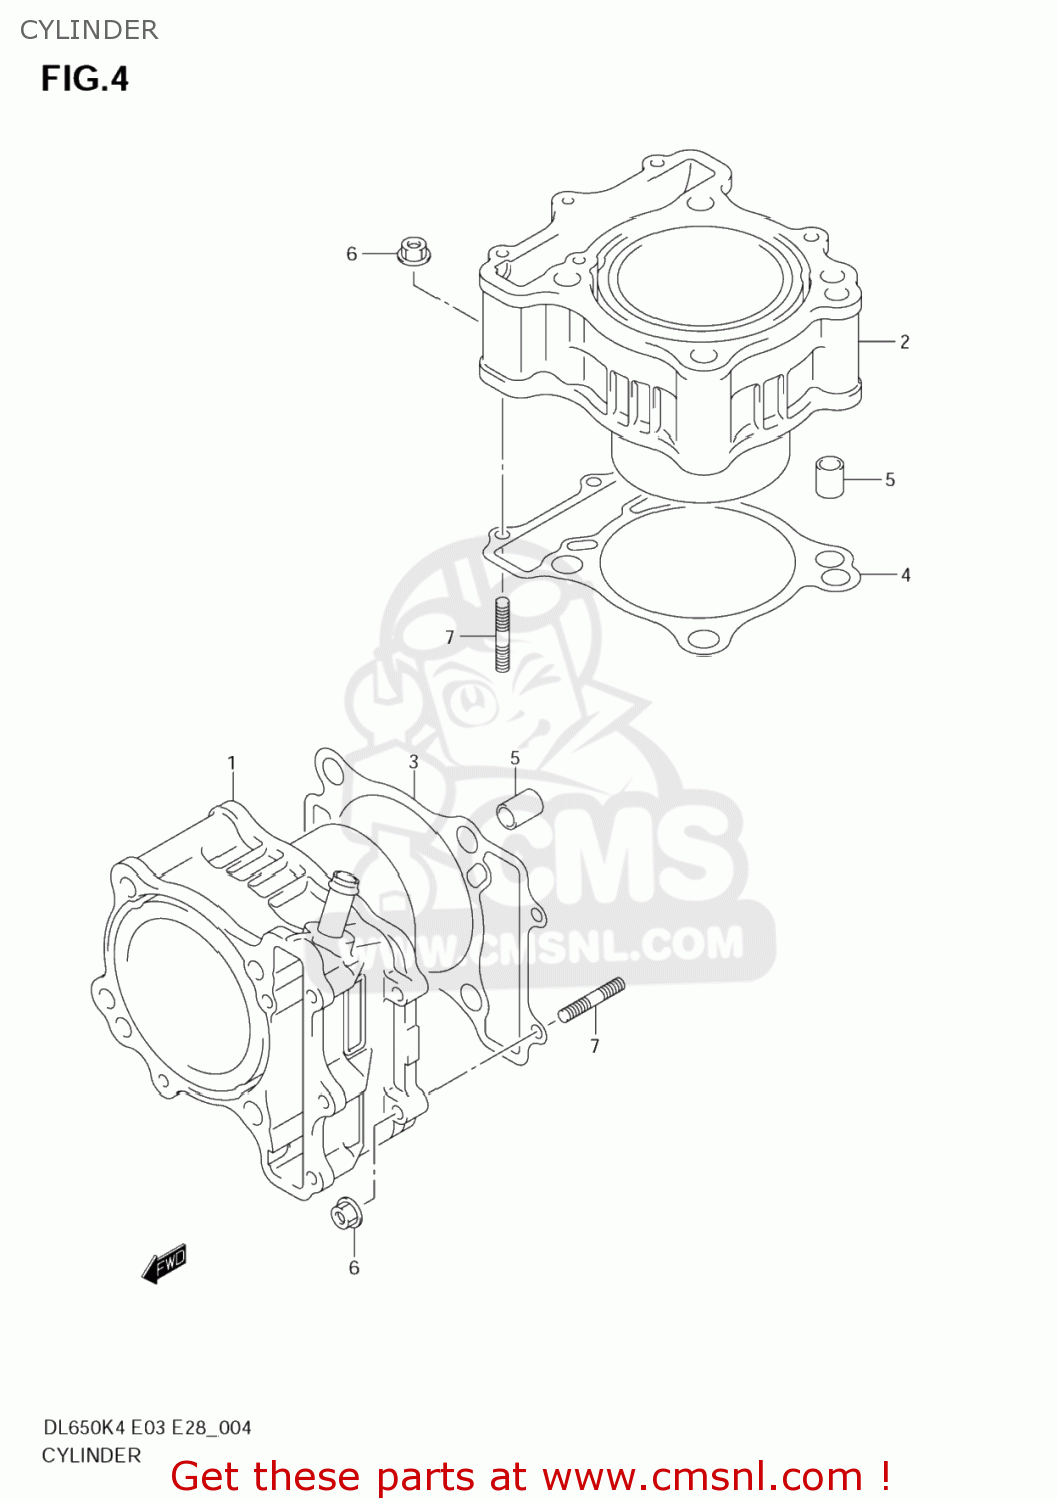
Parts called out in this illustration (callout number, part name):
1	CYLINDER,FR
2	CYLINDER,RR
3	GASKET,CYLINDER FR (NAS)
4	GASKET,CYLINDER RR (NAS)
5	PIN
6	NUT
7	STUD BOLT
